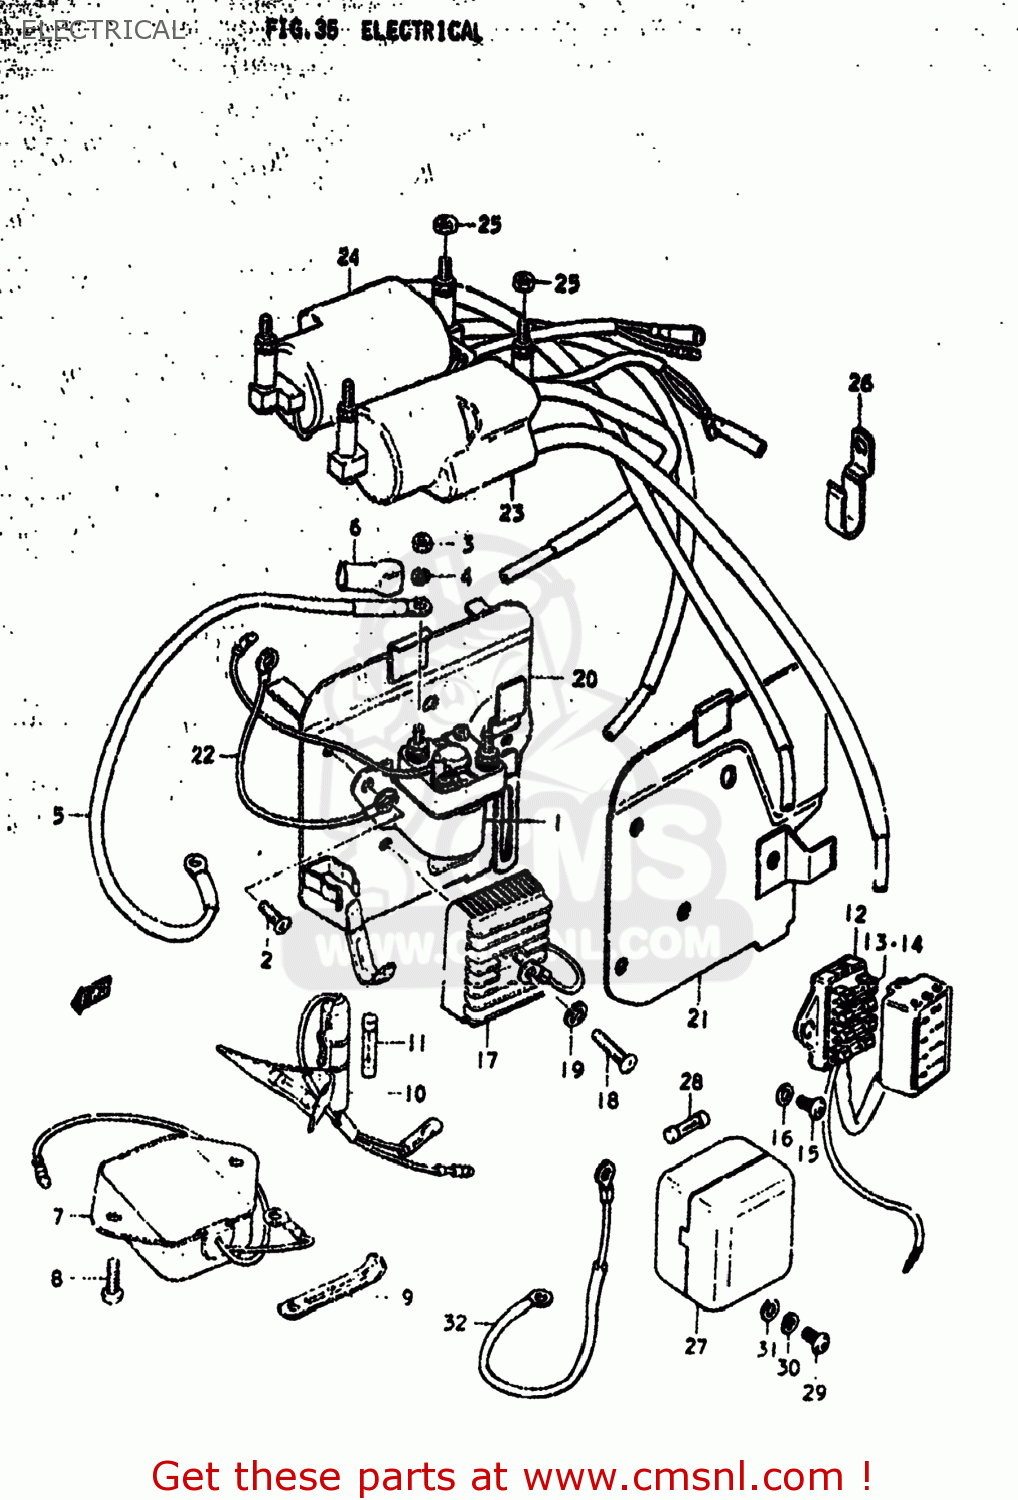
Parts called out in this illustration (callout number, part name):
1	RELAY ASSY,STARTING MOTOR
2	SCREW
3	NUT 6MM
4	LOCK WASHER
5	WIRE,STARTER MOTOR LEAD
6	CAP,STARTER RELAY
7	REGULATOR ASSEMBLY
8	SCREW
9	CLAMP
10	BOX ASSEMBLY,FUSE
11	FUSE(15A)
12	BOX ASSEMBLY,FUSE
13	FUSE(10A)
14	FUSE(15A)
15	SCREW 6X12
16	WASHER
17	RECTIFIER ASSY
18	SCREW
19	LOCK WASHER
20	HOLDER COMP,ELECTRONIC PARTS
21	HOLDER COMP,ELECTRONIC PARTS
22	WIRE
23	COIL ASSEMBLY,IGNITION
24	COIL ASSEMBLY,IGNITION
25	NUT
26	CLAMP
27	TERMINAL ASSEMBLY,POWER SO
28	FUSE(10A)
29	SCREW
30	LOCK WASHER
31	WASHER
32	WIRE,POWER SOURCE LEAD
